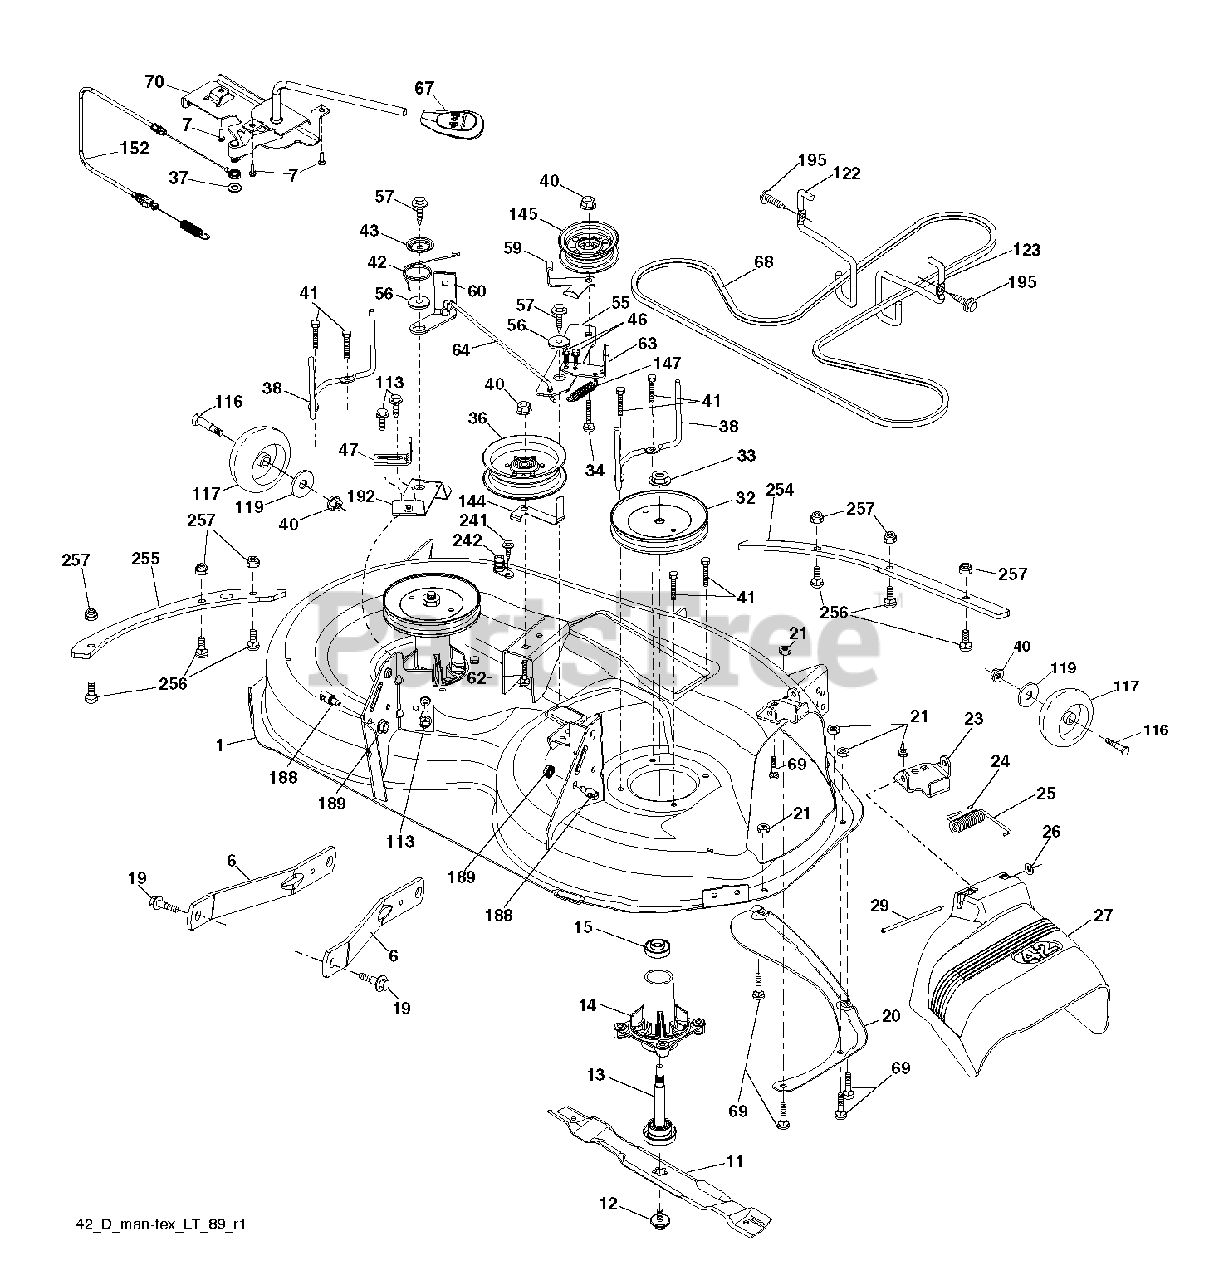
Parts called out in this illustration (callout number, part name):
1	DECK.SVC.42"2GW
6	ARM.SUSPENSION.MOWER.R
7	SCREW.#10 X 0.750.BOS
11	42" HI-LIFT BLADE
12	SCREW.SEMS.7/16-20X1.HEX.HEAD
13	SHAFT ASM.MNDRL.N/GREASEABLE
14	HOUSING.MANDREL.4PT.
15	BEARING.MANDREL.TOP.EXTENDED
19	BOLT.SHOULDER
20	BAFFLE.VORTEX
21	LOCKNUT
23	BRKT.DEFLECTOR.38"2005+
24	CAP-SLEEVE LT
25	SPRING.TORSION.DEFLECT
26	NUT PUSH M
27	SHIELD.DEFLECTOR.MOWER.42"BLAC
29	ROD.HINGE
32	PULLEY.MANDREL.5.438.PD
33	NUT.FLANGE.LOCK.TOP
34	BOLT.3/8-16X1.50
36	PULLEY.IDLER.2006
37	WASHER
38	KEEPER.BELT.MANDREL.PULLEY
40	NUT LOCK FLG 3/8-16 UNC
41	BOLT.HEX.WASHR.HED.313-18X1.19
42	SPRING.TORSION.BRAKE
43	SRPING.TORSION.RETAINE
46	SCREW.1/4-20X5/8
47	BRKT.CLUTCH.CABLE
55	IDLER.ARM.42"
56	SPACER.RETAINER
57	SCREW 3/8-16X1
59	GUARD, BELT
60	ARM BRAKE MOWER
63	ARM BRAKE MOWER
64	LINKAGE.BRAKE.ASM.ZINC
67	HANDLE.CLUTCH.CABLE.LT
68	BELT.DECK.DRIVE.42"
69	BOLT
70	CLUTCH.ASM.MANUAL.YT.PREDATORQ
113	BOLT.5/16HEX.WHS.HD
116	BOLT M
117	Gage Wheel, Rally Narrow
119	WASHER
122	KEEPER BELT ENGINE LH
123	KEEPER BELT RH
144	KEEPER.BELT.MOWER
145	PULLEY.IDLER.48"PRIMARY
147	RETURN SPRING
152	CABLE.CLUTCH.CABLE.W/SPRING
188	STUD.FASTNER.W/ANTI-ROTATE
189	NUT LOCK HEX FLANGE 5/16-18
192	BRKT.BRAKE.STAND.LH.
195	SCREW, 3/8-16X3/4
241	SCREW.TT.#10-32X.5.3/8.FLANGE
242	PORT.WASHOUT
254	PLATES.RENFRC.42DECK.PT431FRNT
255	PLATES.RENFRCE.42DECK.X431SIDE
256	RHSNB, 1/4-20 X 1, GR5
257	NUT T
